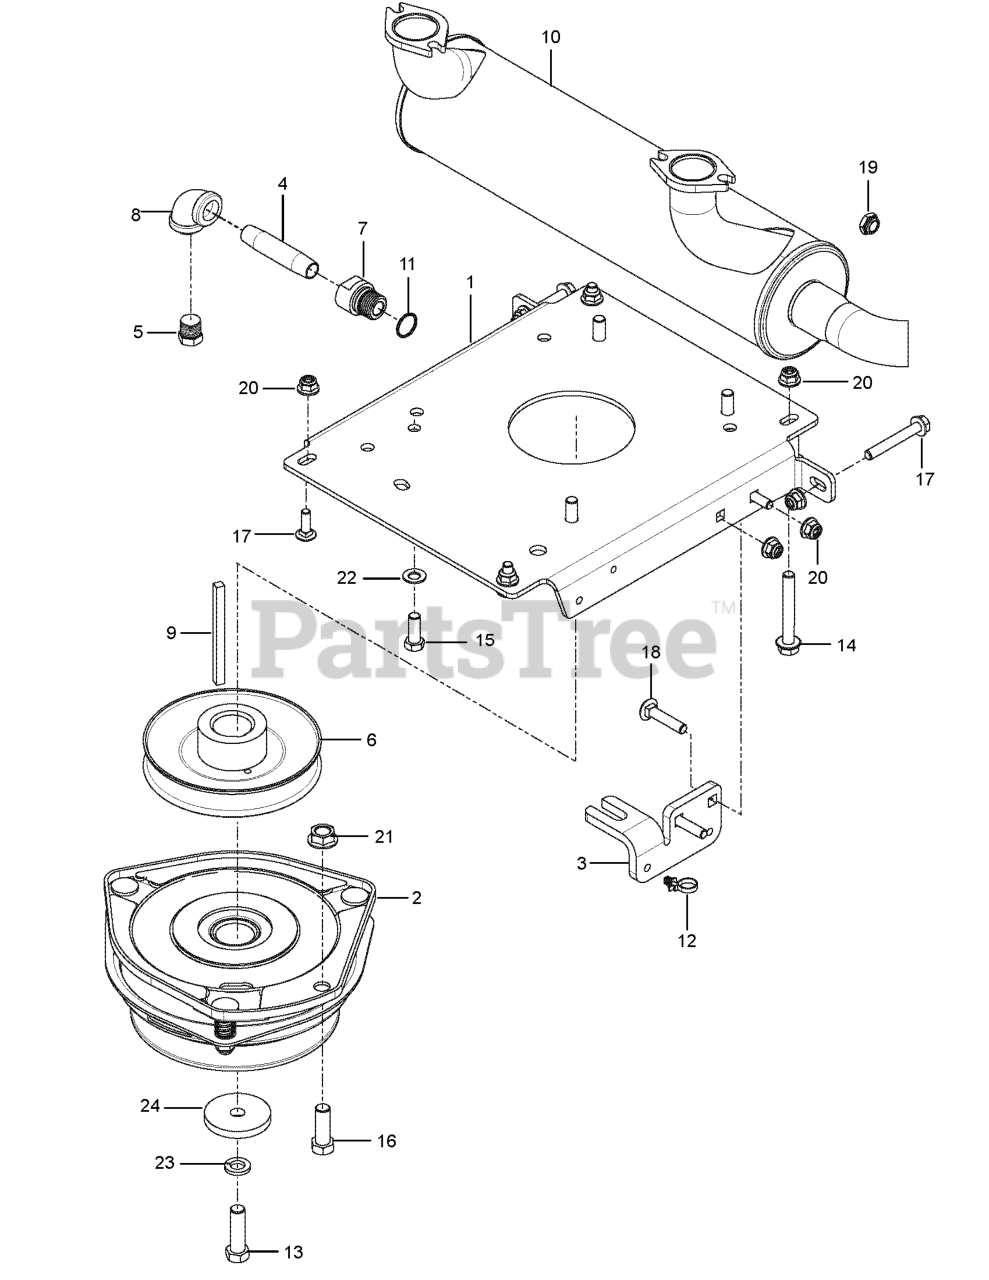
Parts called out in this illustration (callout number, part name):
1	PLATE.PNT.ENGINE.PZ/PZT.EDIP
2	CLUTCH, GT3.5
3	STOP, CLUTCH, OGURA
4	PIPE NIPPLE 3/8 X 3
5	PLUG, DRAIN 3/8 NPTF
6	PULLEY, ENGINE
7	ADAPTER, OIL DRAIN
8	90 DEG.ELBOW 3/8NPT
9	KEY, 1/4 SQ X 3.5
10	MUFFLER, 34HP KAW FX921V-1000V
12	TIE WRAP, 8-3/8", W/CLIP
13	CLUTCH BOLT7/16-20X1.5GR5.96HR
14	HHFS 5/16-18 X 2.25 GD 5
15	HCS 3/8-16X1.GRD.5.ZD
16	BOLT FIN HEX 7/16-14 X 1
17	RHSNB 5/16C X 1
18	RHSNB 5/16-18 X 1-1/2 GR 5 ZD
19	JAM NUT 1/4C (2 2 PW01)
20	5/16-18 NYLOC FLANGE NUT
21	NUT 7/16C WHIZ
22	WASHER, 3/8 DISC SPRING SPEC
23	WASHER 7/16 LOCK
24	BLADE WASHER
